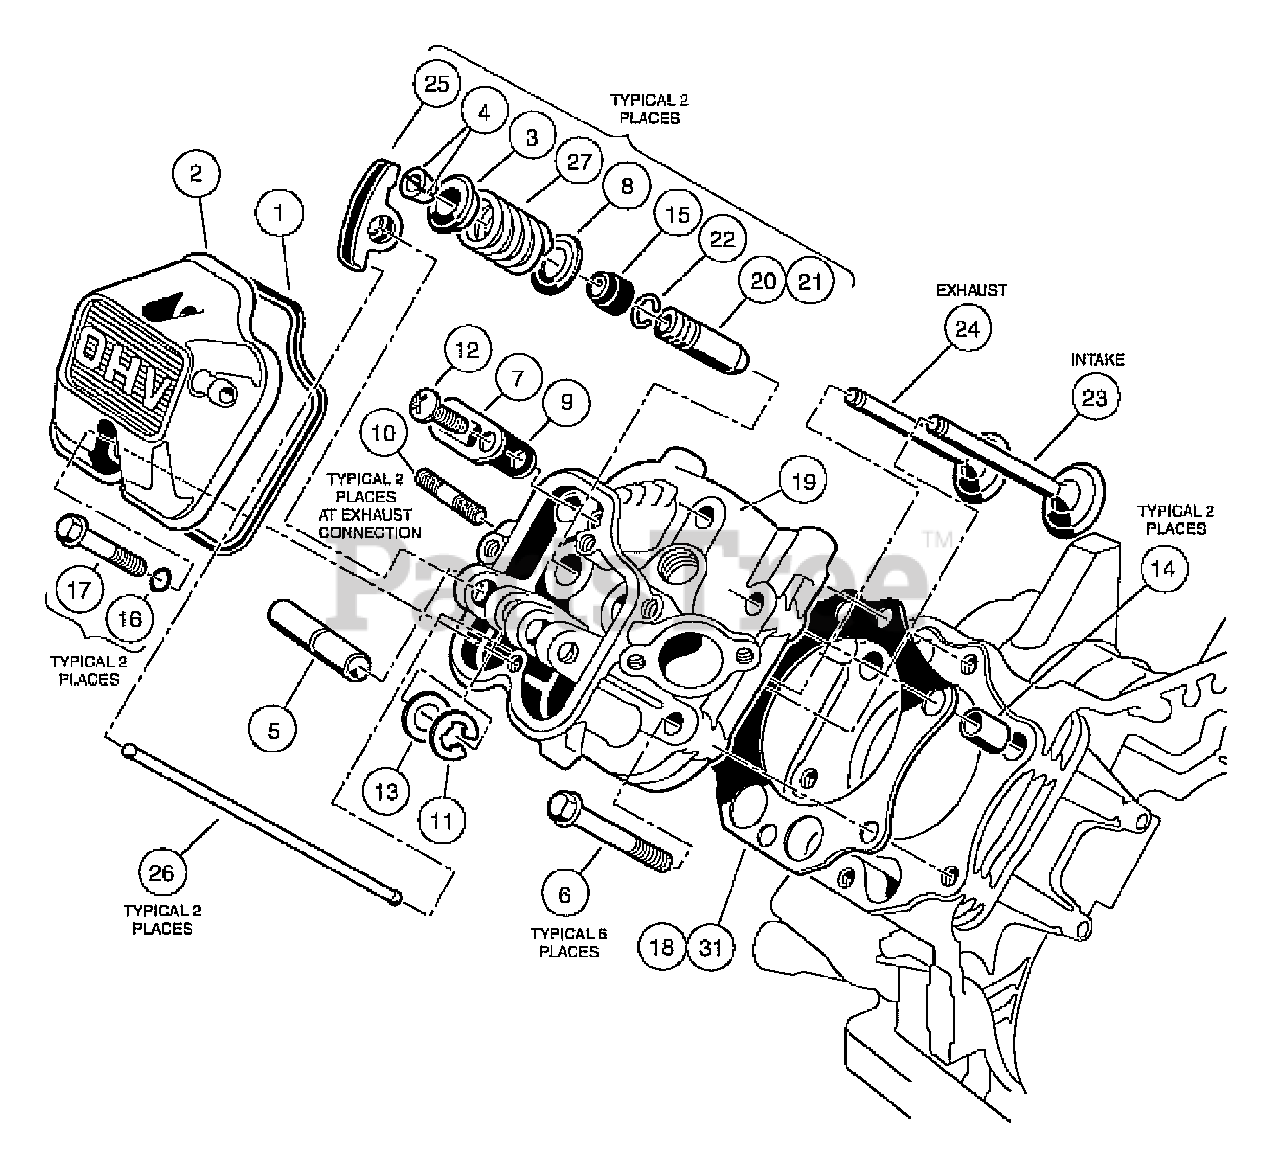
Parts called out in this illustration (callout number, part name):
1	Gasket, Rocker Case
2	Case, Rocker
3	Retainer, Valve Spring
5	Shaft, Rocker
6	Bolt, Flange Head, M8 x 1.25 x 45 mm
8	Seat, Spring
10	Stud, Two-Ended, M8-1.25
11	Circlip, Type-E
13	Washer, 12.lxl9xl.8
17	Bolt, 6x35
18	Gasket, Head
19	Assembly, Cylinder Head, FE350
20	Guide, Valve, Exhaust
21	Guide, Valve, Intake
23	Valve, Intake
24	Valve, Exhaust
25	Arm, Rocker
27	Spring, Engine Valve
28	Kit, Gasket, FE350
29	Gasket, Engine To Insulator
30	Gasket, Exhaust
31	Gasket, Head
32	Gasket, Crankcase Cover
